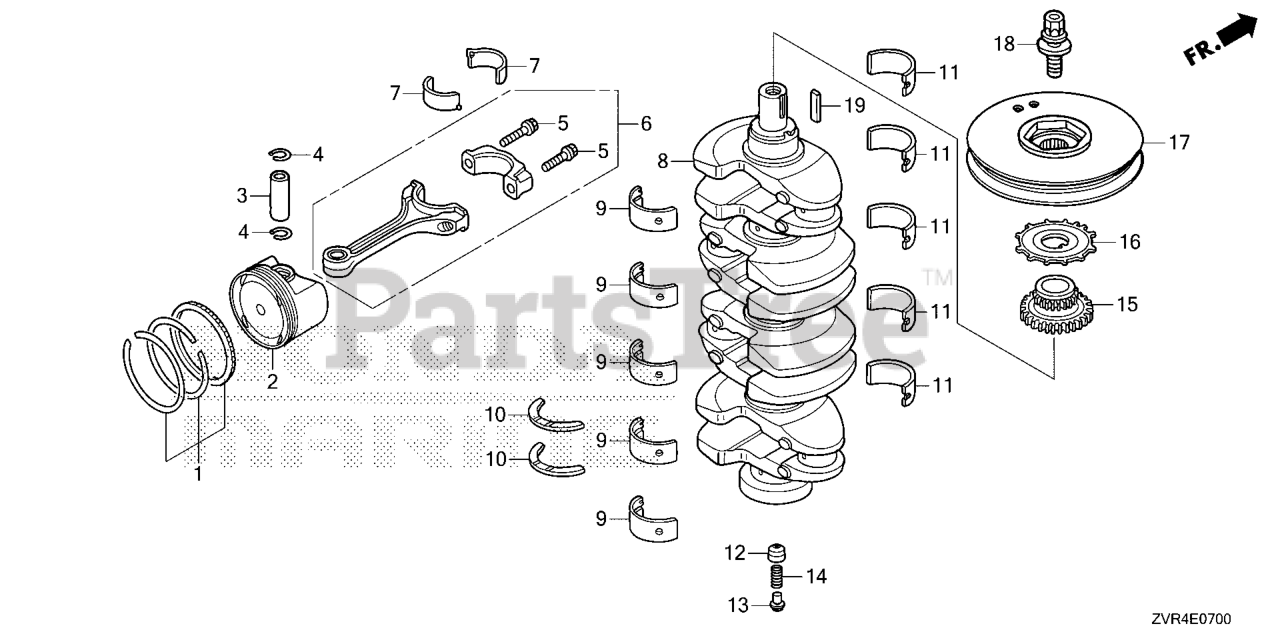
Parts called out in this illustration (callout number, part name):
1	RING SET, PISTON (STD)
3	PIN, PISTON
4	CLIP, PISTON PIN
5	BOLT, CONNECTING ROD (SOURCE: VINTAGE PARTS INC.)
6	ROD, CONNECTING
7	BEARING A, CONNECTING ROD (BLUE)
7	BEARING B, CONNECTING ROD (BLACK)
7	BEARING C, CONNECTING ROD (BROWN)
7	BEARING D, CONNECTING ROD (GREEN)
7	BEARING E, CONNECTING ROD (YELLOW)
7	BEARING F, CONNECTING ROD (PINK)
7	BEARING G, CONNECTING ROD (RED)
8	CRANKSHAFT
9	BEARING A, MAIN (UPPER) (BLUE) (DAIDO)
9	BEARING B, MAIN (UPPER) (BLACK) (DAIDO)
9	BEARING C, MAIN (UPPER) (BROWN) (DAIDO)
9	BEARING D, MAIN (UPPER) (GREEN) (DAIDO)
9	BEARING E, MAIN (UPPER) (YELLOW) (DAIDO)
9	BEARING F, MAIN (UPPER) (PINK) (DAIDO)
10	WASHER, THRUST
11	BEARING A, MAIN (LOWER) (BLUE) (DAIDO)
11	BEARING B, MAIN (LOWER) (BLACK) (DAIDO)
11	BEARING C, MAIN (LOWER) (BROWN) (DAIDO)
11	BEARING D, MAIN (LOWER) (GREEN) (DAIDO)
11	BEARING E, MAIN (LOWER) (YELLOW) (DAIDO)
11	BEARING F, MAIN (LOWER) (PINK) (DAIDO)
12	RETAINER, SPRING
13	SEAT, SPRING (150)
14	SPRING, SUPPORT
15	SPROCKET, CHAIN DRIVE
16	PLATE, CRANK PULSER
17	PULLEY, CRANKSHAFT
18	BOLT-WASHER (16X49)
19	KEY (4.5X21)
